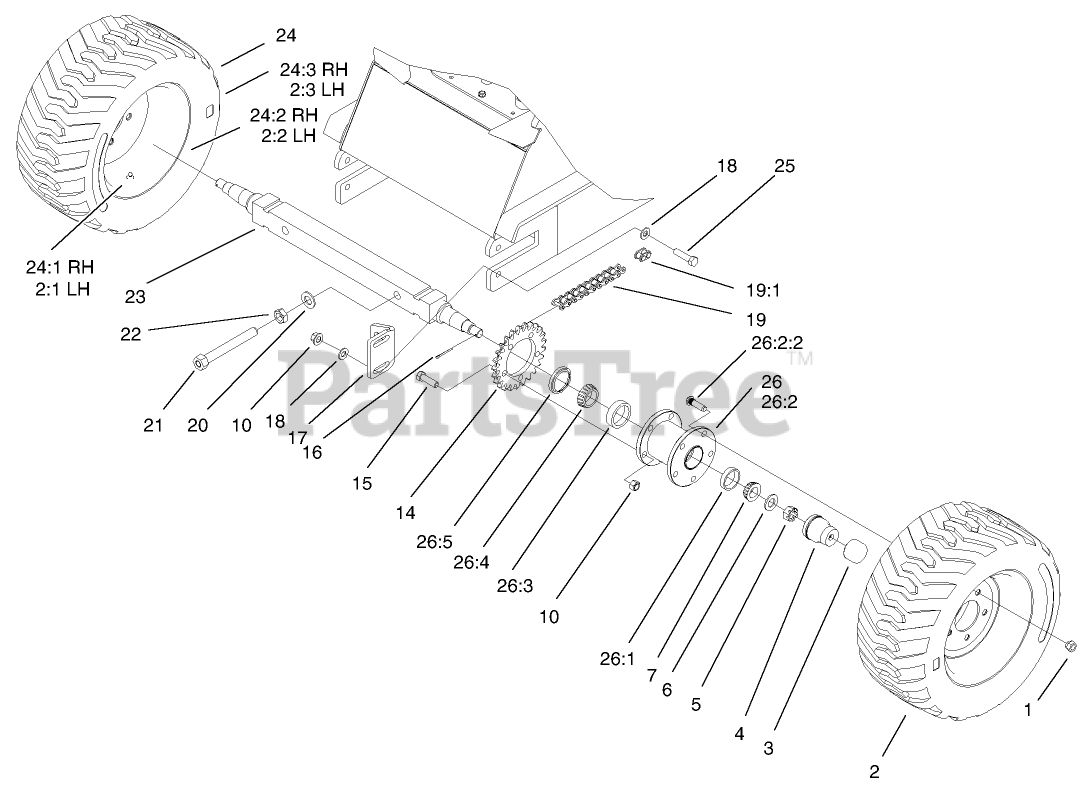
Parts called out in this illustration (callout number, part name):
1	NUT-LUG
2	LH WHEEL AND TIRE ASM
2:1	STEM-VALVE
2:2	WHEEL
3	CAP-PROTECTOR, BEARING
4	PROTECTOR-BEARING
5	NUT-HEX, SLOTTED
6	WASHER-FLAT
7	BEARING-CONE, TAPERED
10	NUT-LOCK, NI
14	SPROCKET-25T
15	SCREW-HH
16	PIN-COTTER
17	BRACKET-AXLE
18	WASHER-FLAT
19	CHAIN-ROLLER
19:1	LINK-CONNECTING
20	WASHER-FLAT
21	BOLT-TENSION
22	NUT-JAM
24	RH WHEEL AND TIRE ASM
24:1	STEM-VALVE
24:2	WHEEL
25	SCREW-HH
26	Hub-Front
26:1	BEARING-CUP, TAPERED
26:2	FRONT HUB ASM
26:2:2	STUD-TYPE, DRIVE
26:3	CUP-BEARING, TAPERED
26:4	CONE-BEARING, TAPERED
26:5	SEAL-BEARING, WHEEL
